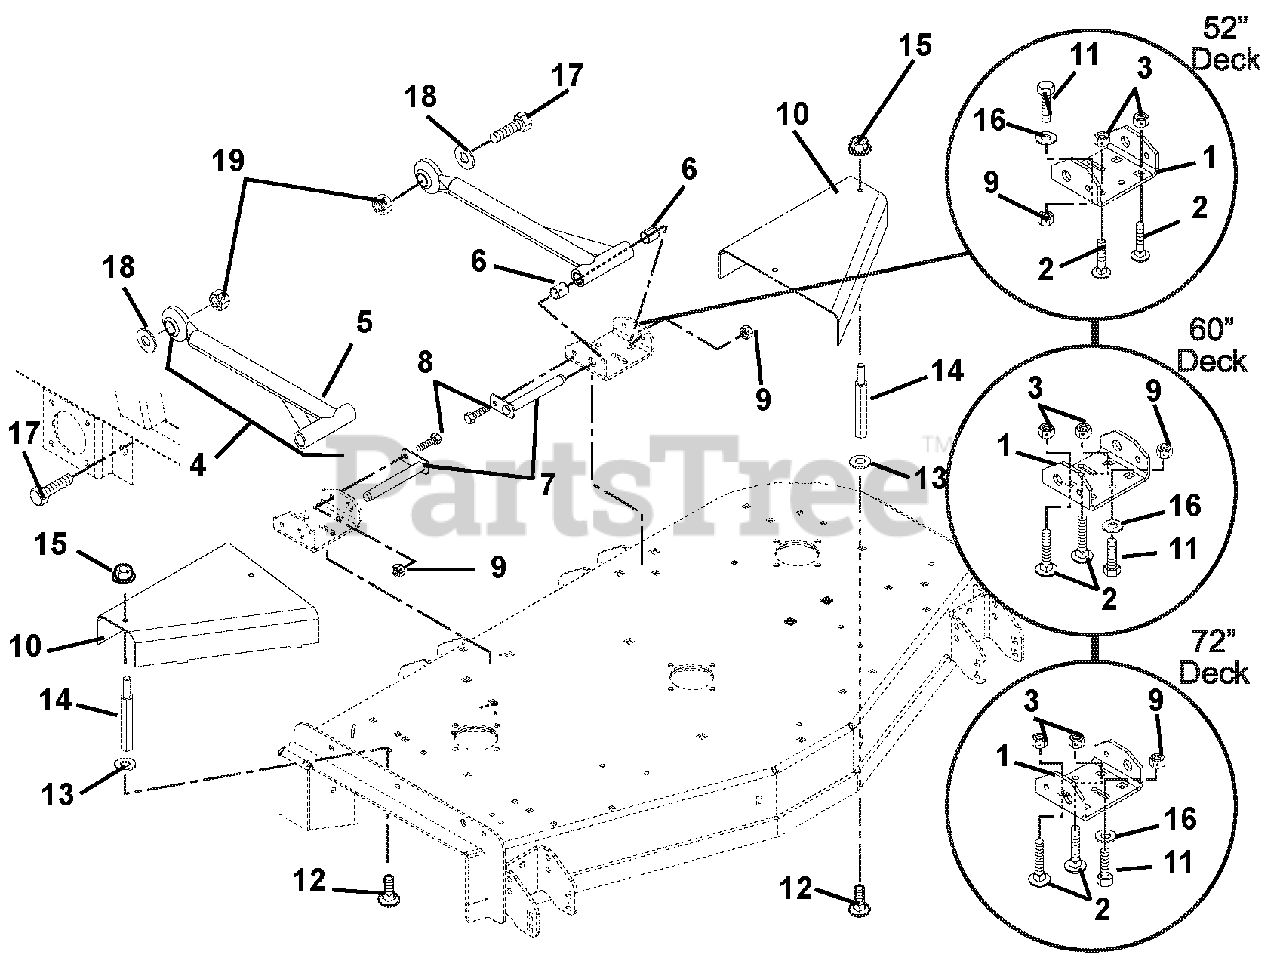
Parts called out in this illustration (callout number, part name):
1	Bracket, Mower Mounting (Rear)
2	Bolt, Round Head Square Neck .50-13 x 1.00 Grade 5
3	Nut, Locking Center Jam .50-13
4	Assembly, Mower Mounting Arm (Includes Items 5 and 6)
5	Weldment, Mower Mounting Arm
6	Bearing .75 x .875 x 1.00
7	Weldment, Mower Mounting Pin
8	Bolt, Hex .38-16 x .75 Grade 5
9	Nut, Locking Top Flange .38-16
10	Guard, Pulley Right Hand (045, 052, 066, 071)
11	Bolt, Hex .38-16 x 1.00 Grade 5
12	Bolt, Round Head Square Neck .31-18 x .75 Grade 5
13	Washer, Flat Steel .38 x .87 x .179
14	Standoff, 2.75 x .312-18
15	Nut, Locking Top Flange .31-18
16	Washer, Flat Steel .406 x .812 x .065
17	Bolt, Hex .875-9 x 2.75 Grade 5
18	Washer, Flat Steel .875 x 1.50 x .120
19	Nut, Locking Center .875-9
